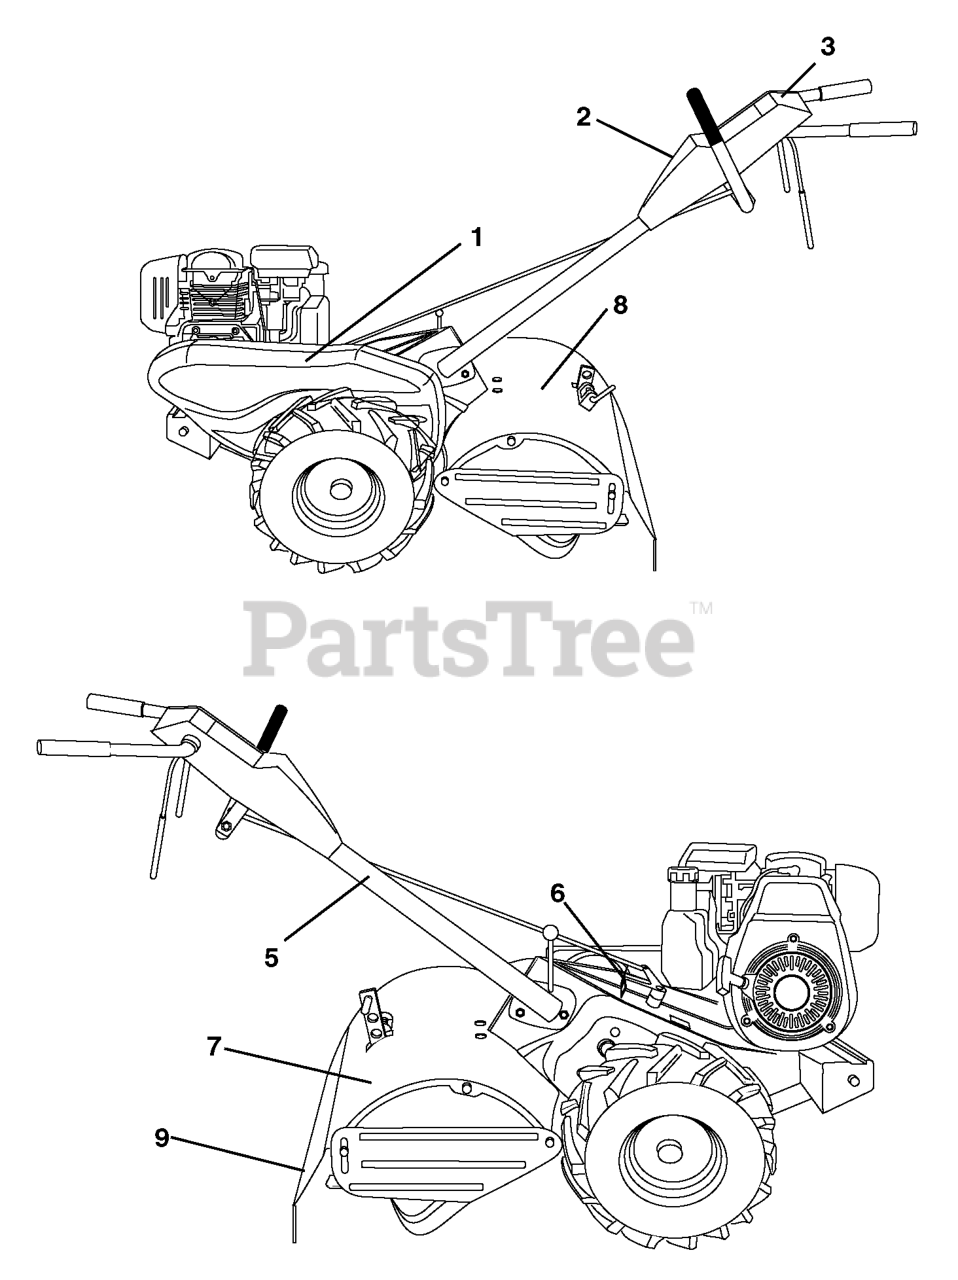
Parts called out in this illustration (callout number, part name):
2	DECAL, LOGO
3	DECAL, CONTROL PNL
5	DECAL TI (2 2)
6	DECAL.SHIFT.INDICATOR.TILLER
7	DECAL -CAUTION
8	DECAL, TINESHEILD
9	DECAL TI
